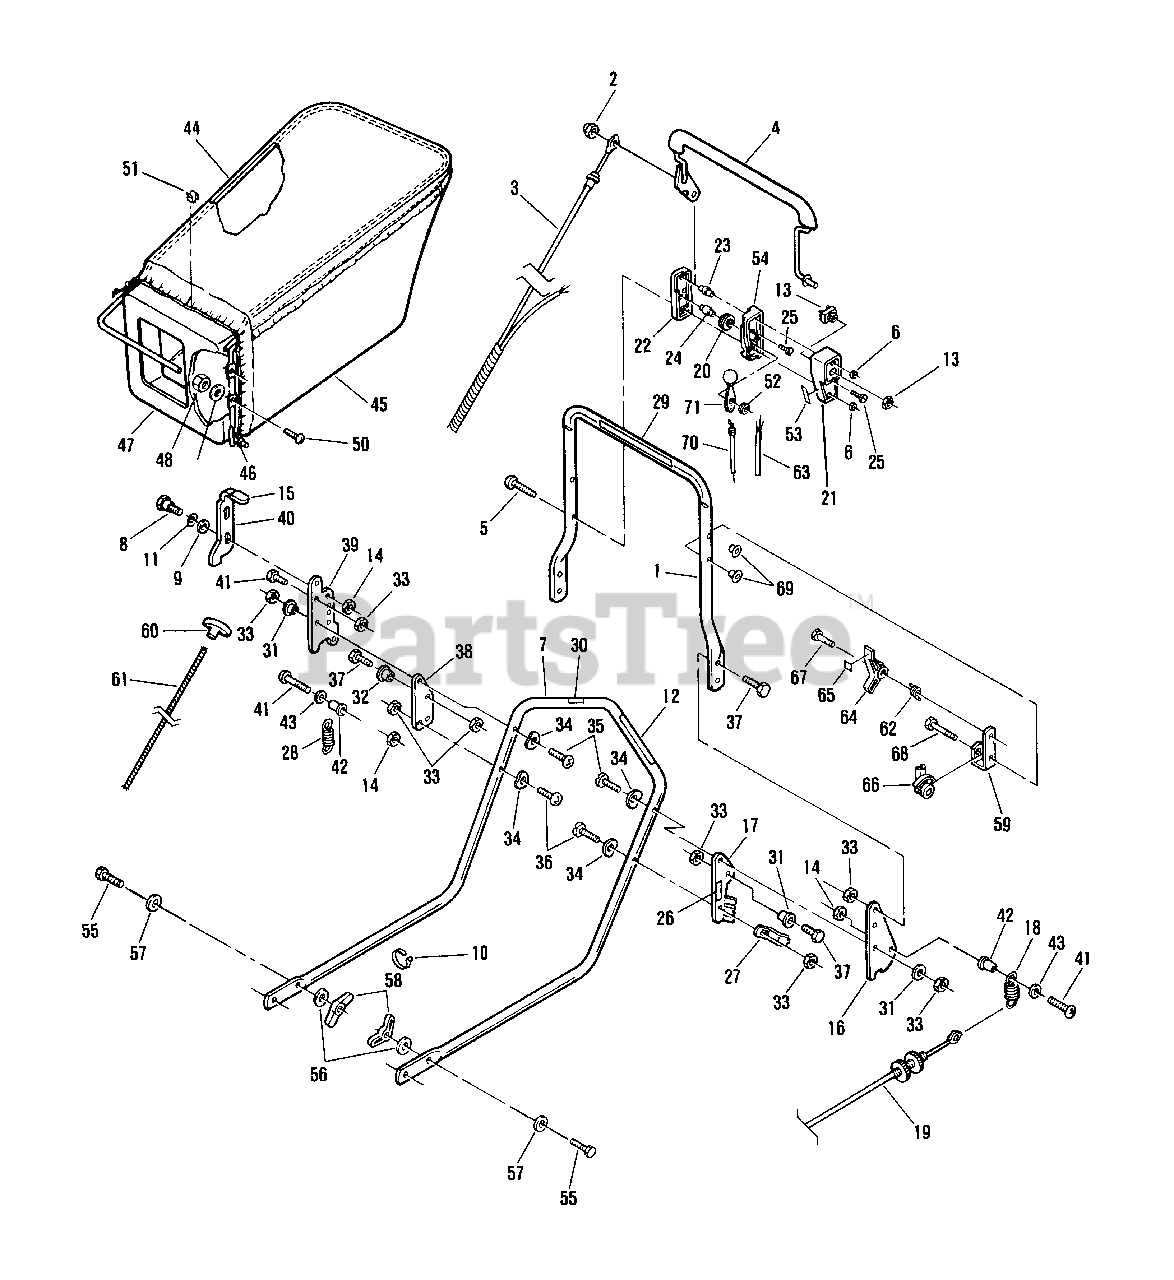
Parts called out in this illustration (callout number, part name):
1	Handle Section-Top
2	Acorn Nut
3	Control Cable Assembly
4	Control Lever Assembly
5	Truss Head Screw
6	Hex Locknut
7	Handle-Lower
8	Bolt-Shoulder
9	Washer
10	Tie Strap
11	Washer-Wave
12	Decal-Starting Instructions
13	Switch Assembly
14	Locknut
15	Knob
16	Plate-Limit
17	Plate-Cable
18	Spring-Cable
19	Cable Assembly
20	Pulley
21	Control Case-Inner
22	Control Case-Outer
23	Column
24	Pin
25	Truss Head Screw
26	Decal-Drive Adjustment
27	Clamp-Cable
28	Spring-Return
29	Decal-Drive Control
30	Decal-Drive Lockout
31	Bushing
32	Bushing
33	Locknut
34	Washer-Curved
35	Truss Head Screw
36	Truss Head Screw
37	Screw
38	Pivot Plate
39	Limit Plate-Right
40	Slide Latch
41	Screw-Truss Head Machine
42	Spacer-Flanged
43	Washer
44	Hanger-Bag
45	Grass Bag Assembly
46	Latch Bar Assembly
47	Bag Adapter
48	Nut-Bag Adapter
49	Washer
50	Screw-Bar Adapter
51	"S" Clip
52	Washer-Spring
53	Decal-Throttle Control
54	Case Control-Center
55	Screw
56	Lockwasher
57	Washer
58	Wing Nut
59	Bracket-Bail Stop
60	Handle
61	Rope
62	Spring-Torsion
63	Wire Harness Assembly-Upper
64	Stop Latch Lever
65	Decal-Latch Lever
66	Cam-Clutch Control
67	Bolt-Shoulder
68	Bolt-Shoulder
69	Nut-Tube
70	Cable-Throttle
71	Lever and Knob Assembly-Throttle
